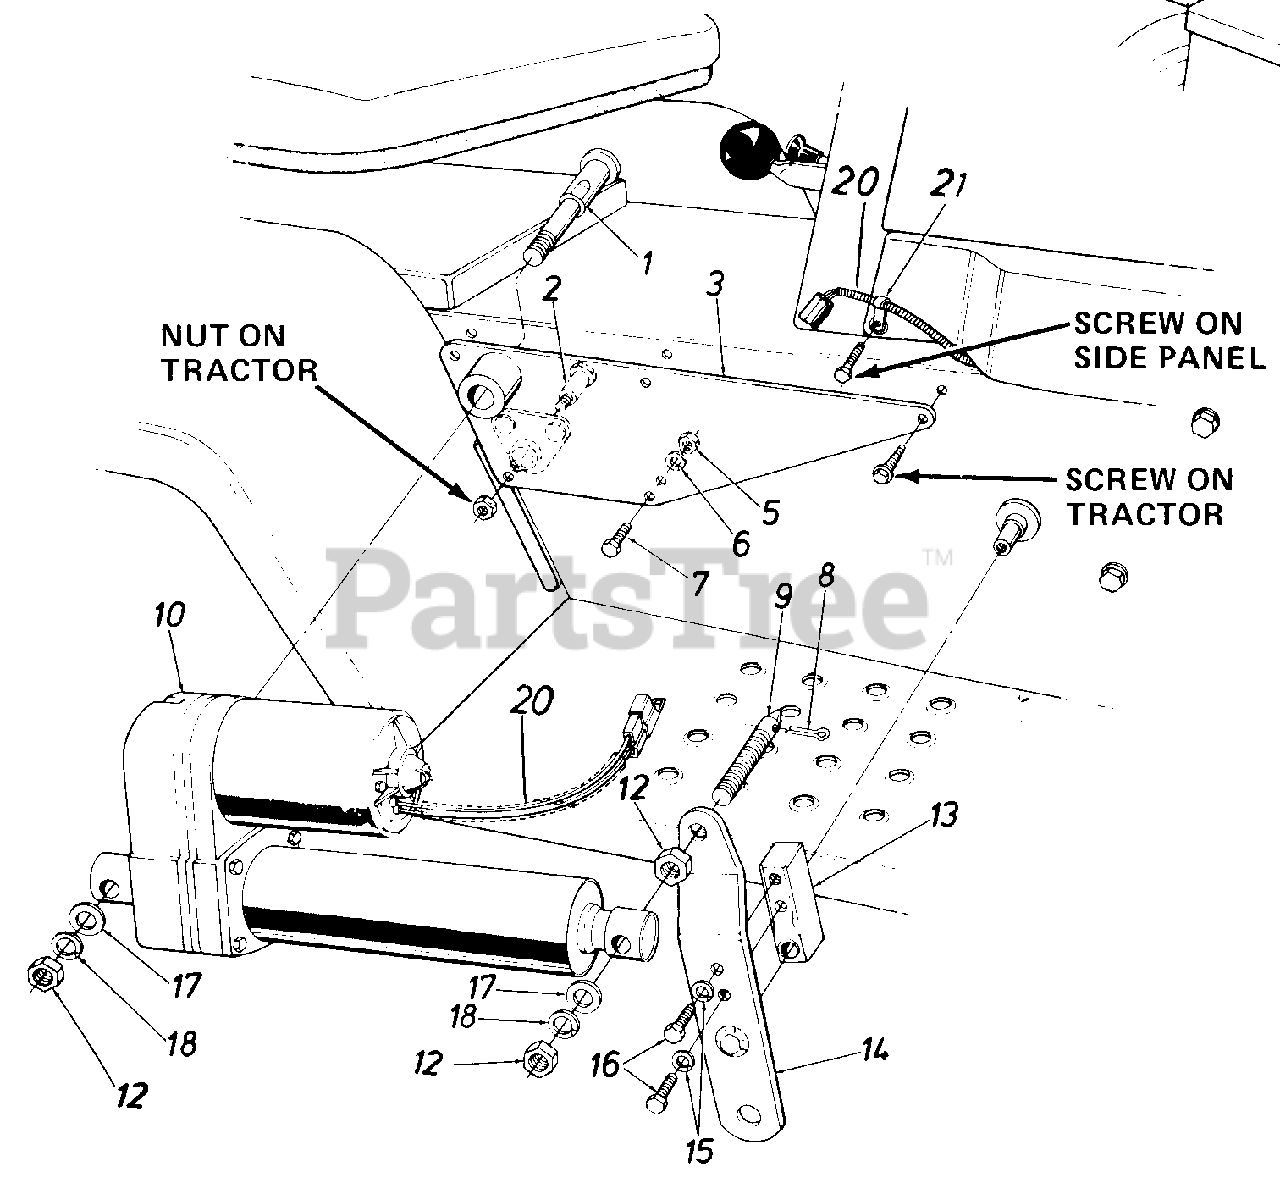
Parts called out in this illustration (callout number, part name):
1	Pivot Pin
2	Shld. Bolt.626 Dia. x .96"
5	Hex Nut 1/4-28 Thd.
6	L-Wash. 1/4" I.D.
7	Hex Bolt 1/4-28 x .75" Lg. (Grade 5)
8	Cotter Pin
9	Indicator & Mtg. Pin
10	Electric Actuator
12	Hex Jam Nut 1/2-13 Thd.
13	Lift Shaft Drive
16	Hex Bolt 5/16-24 x 1.0" Lg.
17	Fl-Wash. .53" I.D. x.93" O.D.
18	L-Wash. 1/2" I.D.
20	Plastic Tubing-7"
21	Clamp
